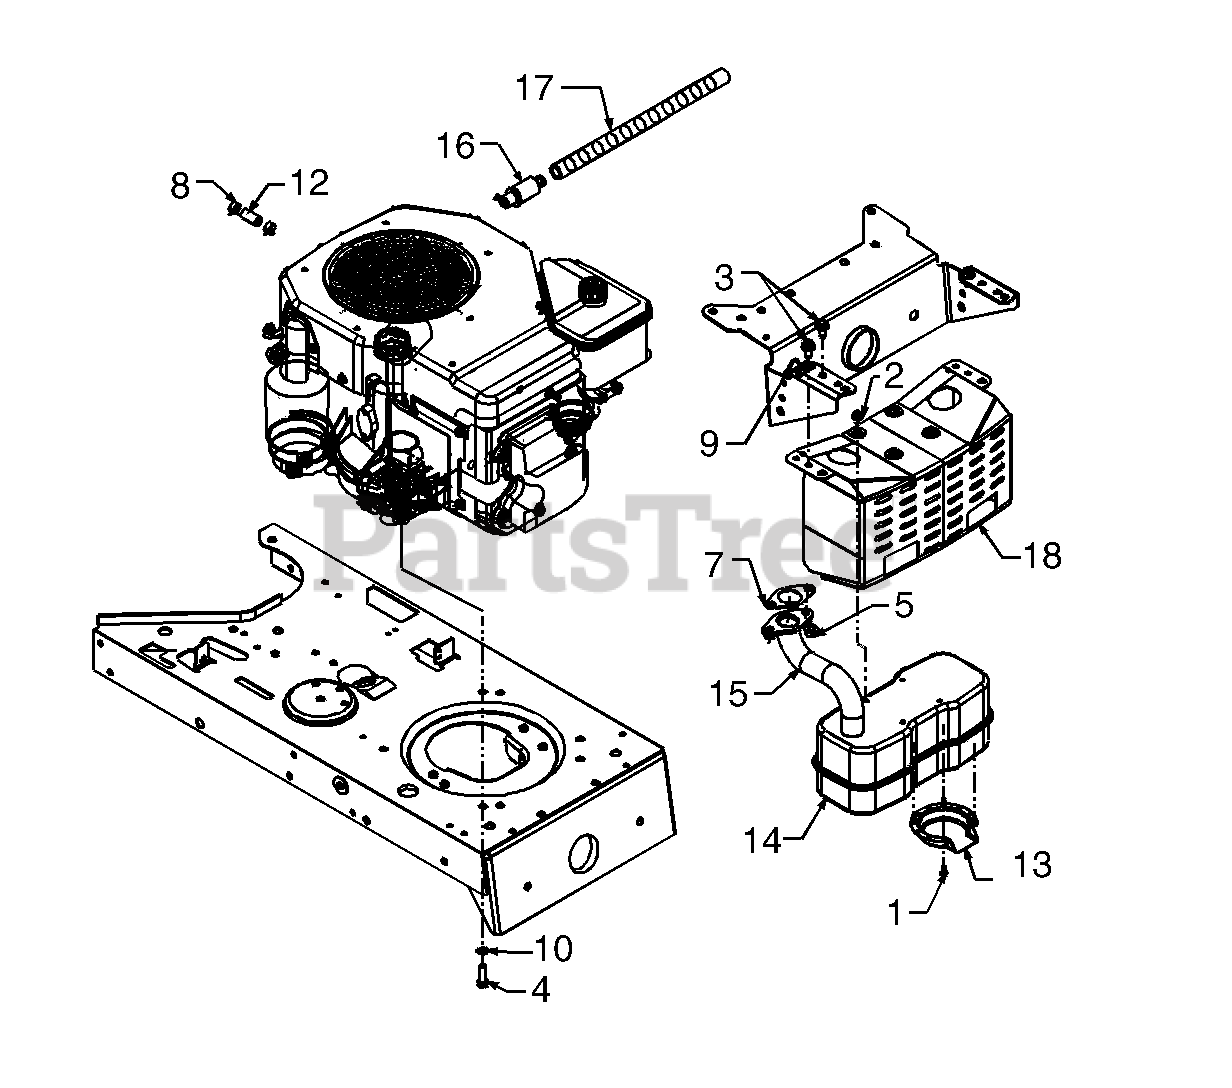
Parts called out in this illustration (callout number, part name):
1	Hex Tap Scr. #8-32 x .38" Lg.
2	Hex Wash. TT-Tap Scr. 1/4-20 x5" Lg.
3	Hex Wash. TT-Tap Scr. 5/16-18 x .62" Lg.
4	Hex Bolt M8 x 1.25
5	Hex Flange Nut M8 Thd.
7	Exhaust Gasket
8	Hose Clamp
9	Clamp
10	External L-Wash. 5/16" I.D.
12	Fuel Line 12" Lg.
13	Muffler Deflector
14	Muffler
15	Exhaust Pipe
16	Oil Drain
17	Oil Drain Hose
